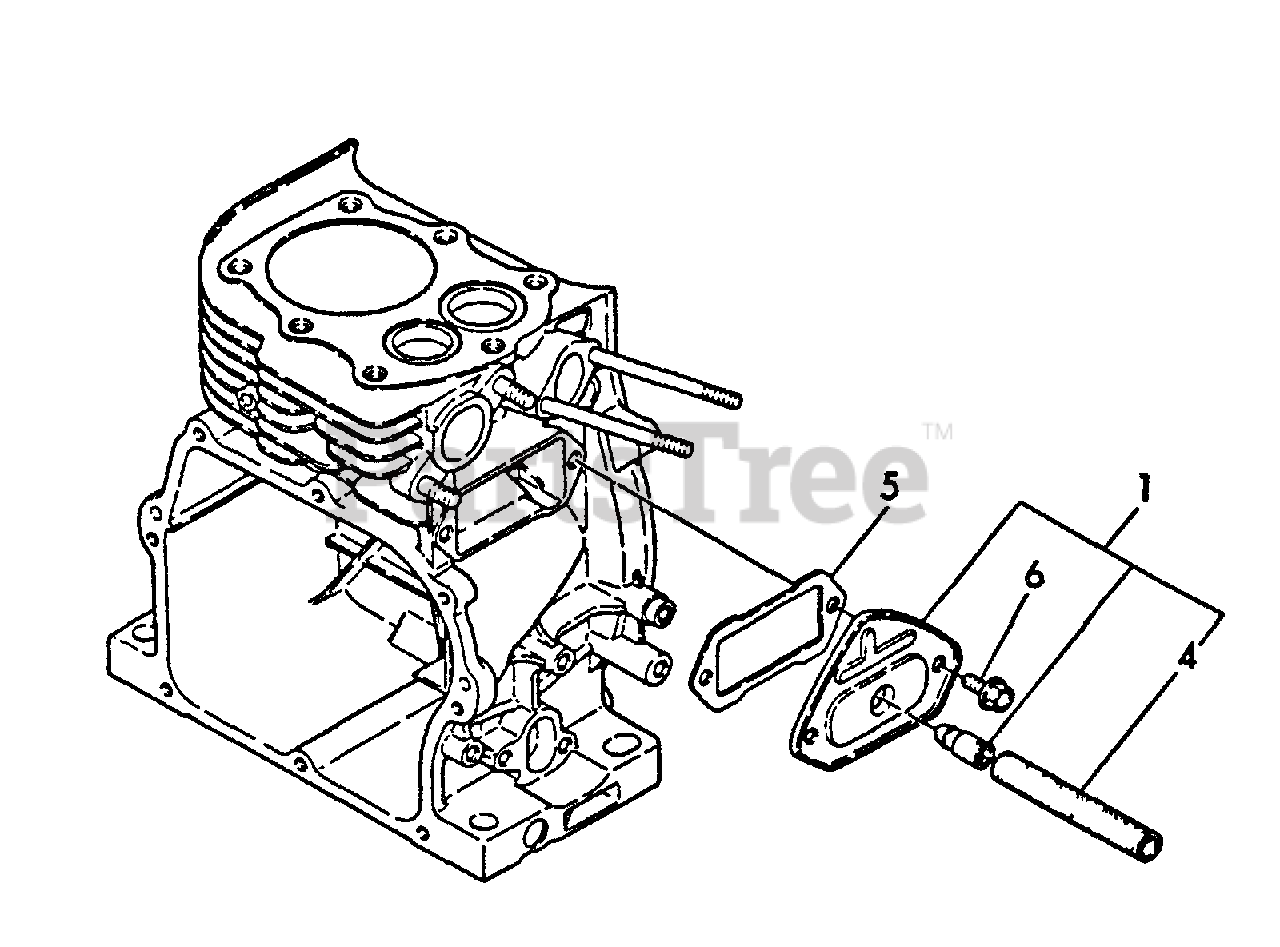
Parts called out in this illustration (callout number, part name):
1	VENT, FUEL TANK
4	PIPE - BREATHER
5	GASKET, BREATHER
6	BOLT - 6X8 -- PLATED
